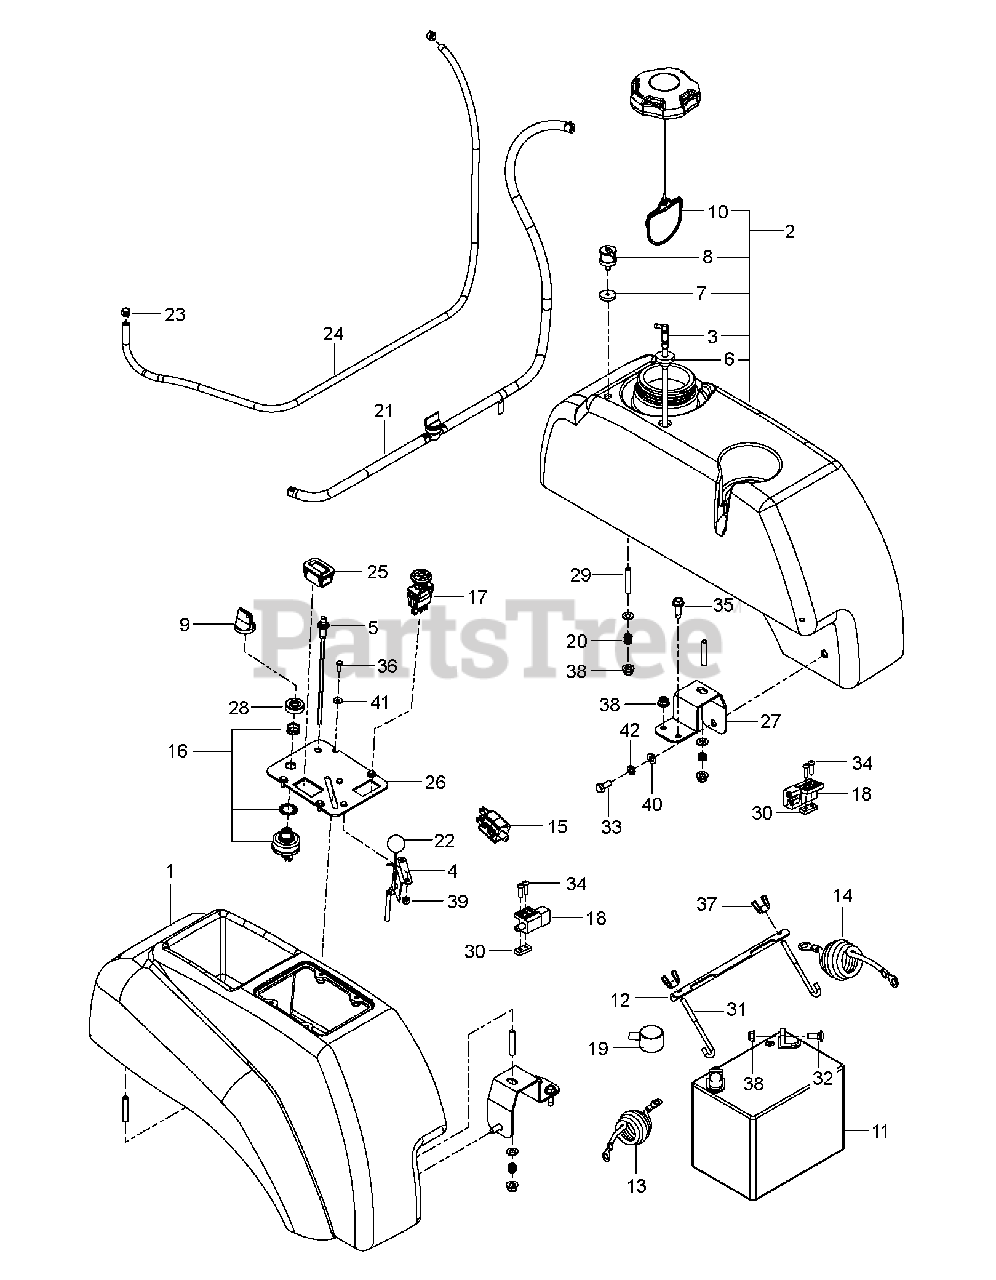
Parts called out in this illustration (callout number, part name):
1	FENDER CONSOLE
2	FUEL.TANK.ASSY.LH.MZ.GRY
3	FITTING, FUEL
4	THROTTLE CONTROL W/BALL KNOB
5	LED.LIGHT.SERVICE.EFI
6	RUBBER GROMMET
7	GROMMET, CHECK VALVE
8	VALVE.FUEL.CHECK
9	KEY, IGNITION
10	CAP, FUEL
11	BATTERY, 12 V 330 AMP
12	BRACKET.BATTERY.MOUNT.PLATED
13	CABLE.BATT.SOLENOID.MZ.RED.25"
14	CABLE.GROUND.BATT.MZ.BLACK.39"
15	SWITCH, BRAKE 3P
16	SWITCH, IGNITION, INDAK
17	SWITCH, PTO 10 AMP
18	SWITCH INTERLOCKT
19	COVER.TERMINAL.BATTERY
21	FUEL.HOSE.SHUT.OFF.ASM.10".26"
22	KNOB.ROUND.BALL.BLACK
23	CLAMP, HOSE
24	HOSE.3/16".VAPOR.LINE.39"LGTH
25	GUAGE.SRVCMNDR.HRMTR.
26	PLATE, CONSOLE, BLK
27	SUPPORT, TANK, BLK
28	CAP IGNITION NUT
29	STUD, 5/16C
30	PLATE NUT ZTR
32	BOLT 5/16-18 X3/4 ZN/YEL GR 5
33	BOLT
34	SCR #10-24 X .75 SKT HD BLK
35	SCREW
36	HCS #10-24 X 1/2
37	WING NUT 1/4
38	5/16-18 NYLOC FLANGE NUT
39	NUT 10-24 NYLOC
40	WASHER
42	WASH.5/16.SLW.ZD
